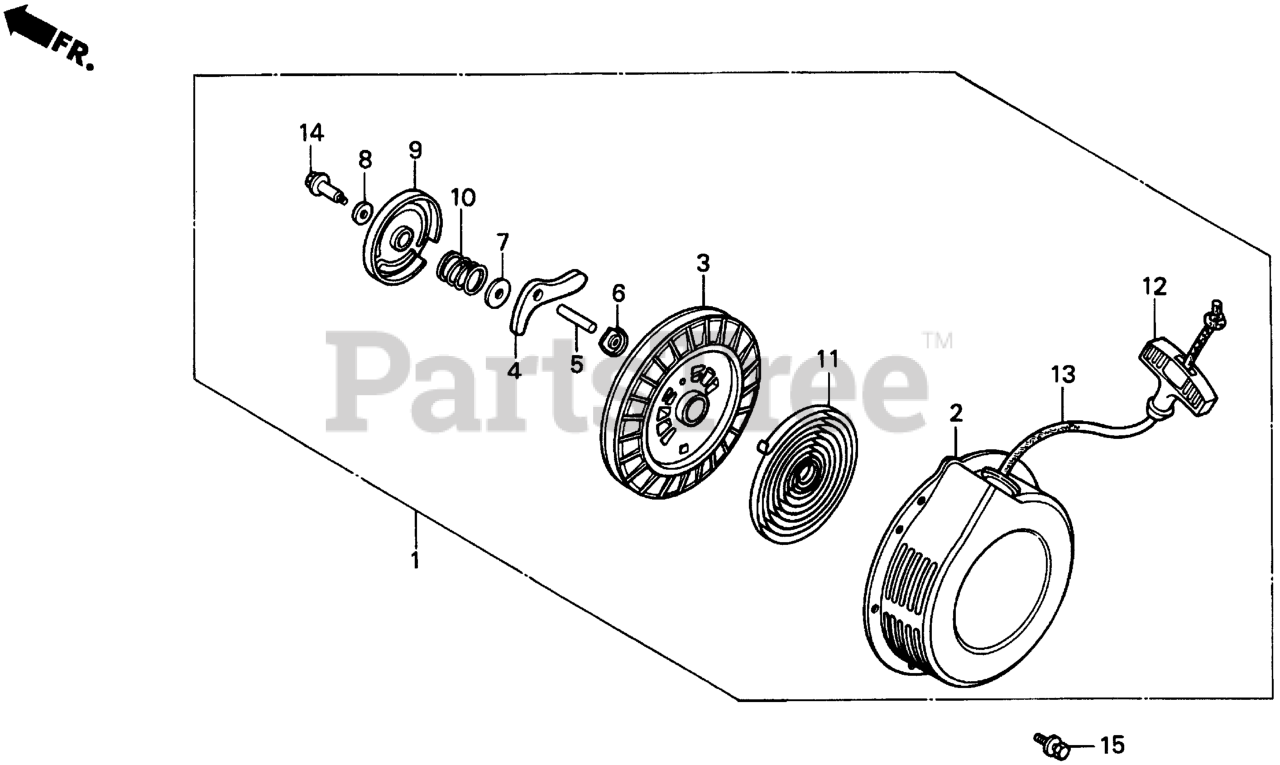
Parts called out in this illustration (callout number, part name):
1	STARTER ASSY., RECOIL
2	CASE, RECOIL STARTER *R8* (BRIGHT RED)
3	REEL, STARTER
4	RATCHET, STARTER
5	SHAFT, RATCHET
6	PLATE, GUIDE
7	PLATE A, FRICTION
8	PLATE B, FRICTION
9	COVER, REEL STARTER
10	SPRING, FRICTION
11	SPRING, RETURN
12	GRIP, STARTER
13	ROPE, RECOIL STARTER (#5X59") (NA USE ALT:08550-ZG921-11)
14	BOLT, REEL COVER
15	BOLT-WASHER (6X10)
